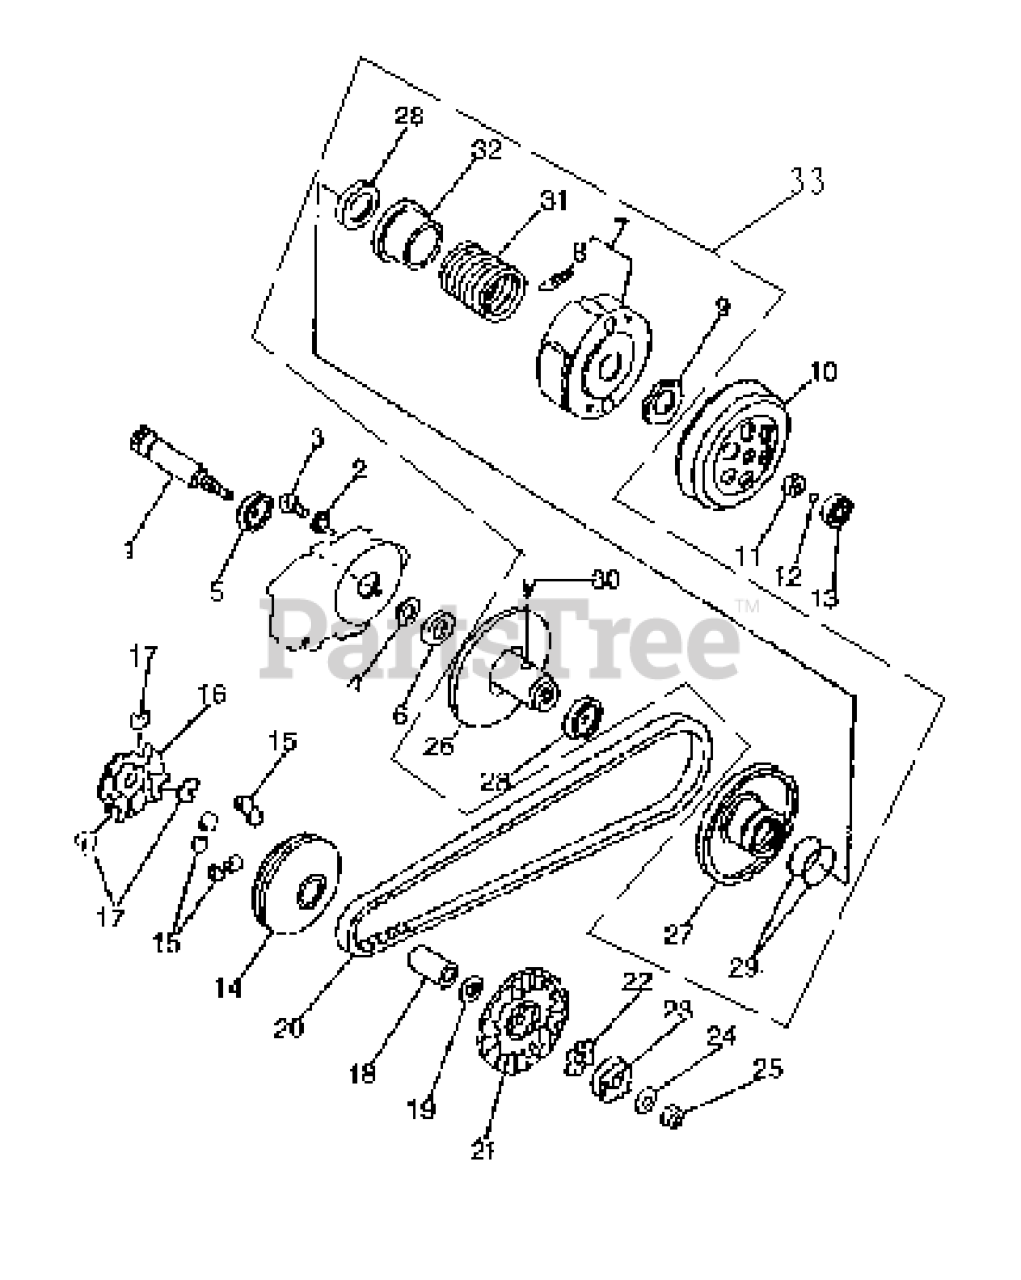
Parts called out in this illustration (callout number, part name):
1	PRIMARY DRIVE GEAR
4	CIRCLIP
5	ROLING BEARING
6	OIL SEAL
7	SHOE, CLUTCH ASSY.
8	SPRING
10	HOUSING
13	BEARING
14	FACE, MOVABLE DRIVE
16	PLATE, MOVABLE DRIVE
17	DAMPER
20	V BELT, DRIVE
21	FACE, FIXED DRIVE
22	PLATE, WOODRUFF KEY
23	STARTING DISC
24	WASHER, SPRING
26	FACE, FIXED DRIVEN
27	FACE, MOVABLE DRIVEN
28	OIL SEAL
30	PIN, GUIDE
32	SEAT, SPRING
33	DRIVEN PULLEY and CLUTCH ASSY
